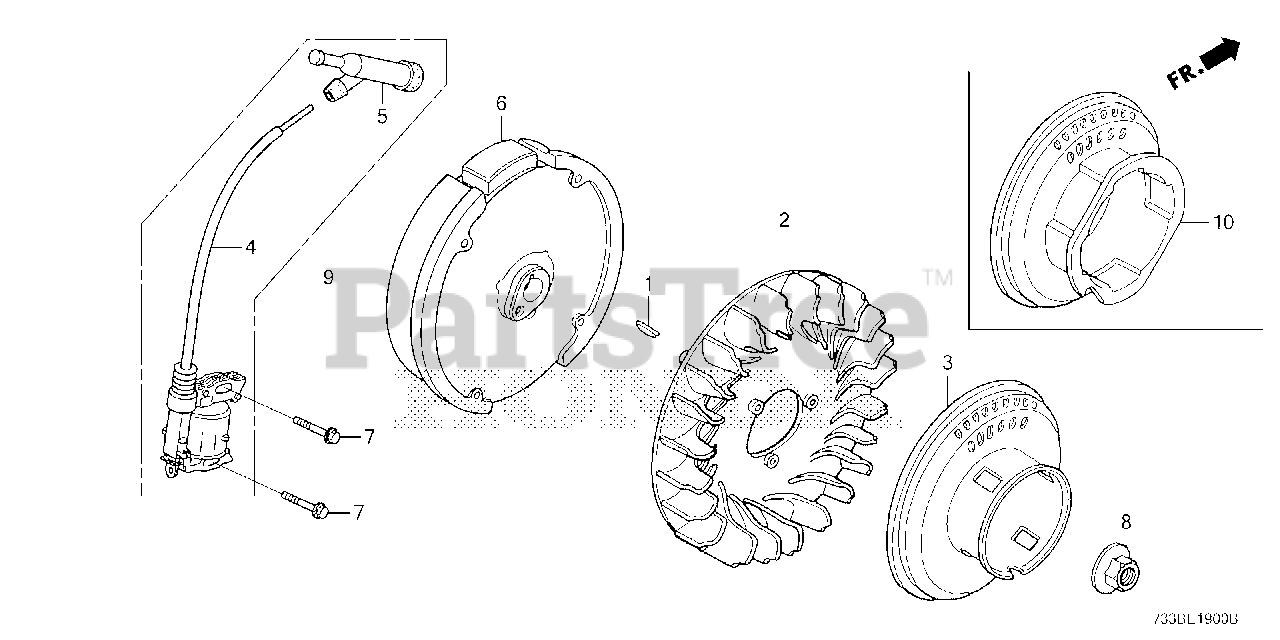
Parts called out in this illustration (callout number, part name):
1	KEY, SPECIAL WOODRUFF (25X18)
2	FAN, COOLING
3	PULLEY, STARTER
4	COIL ASSY., IGNITION (TEC)
5	CAP ASSY., NOISE SUPPRESSOR (TEC)
7	BOLT, FLANGE (6X25) Use up to Engine SN 2056819.
8	NUT, SPECIAL (14MM)
10	PULLEY, STARTER
